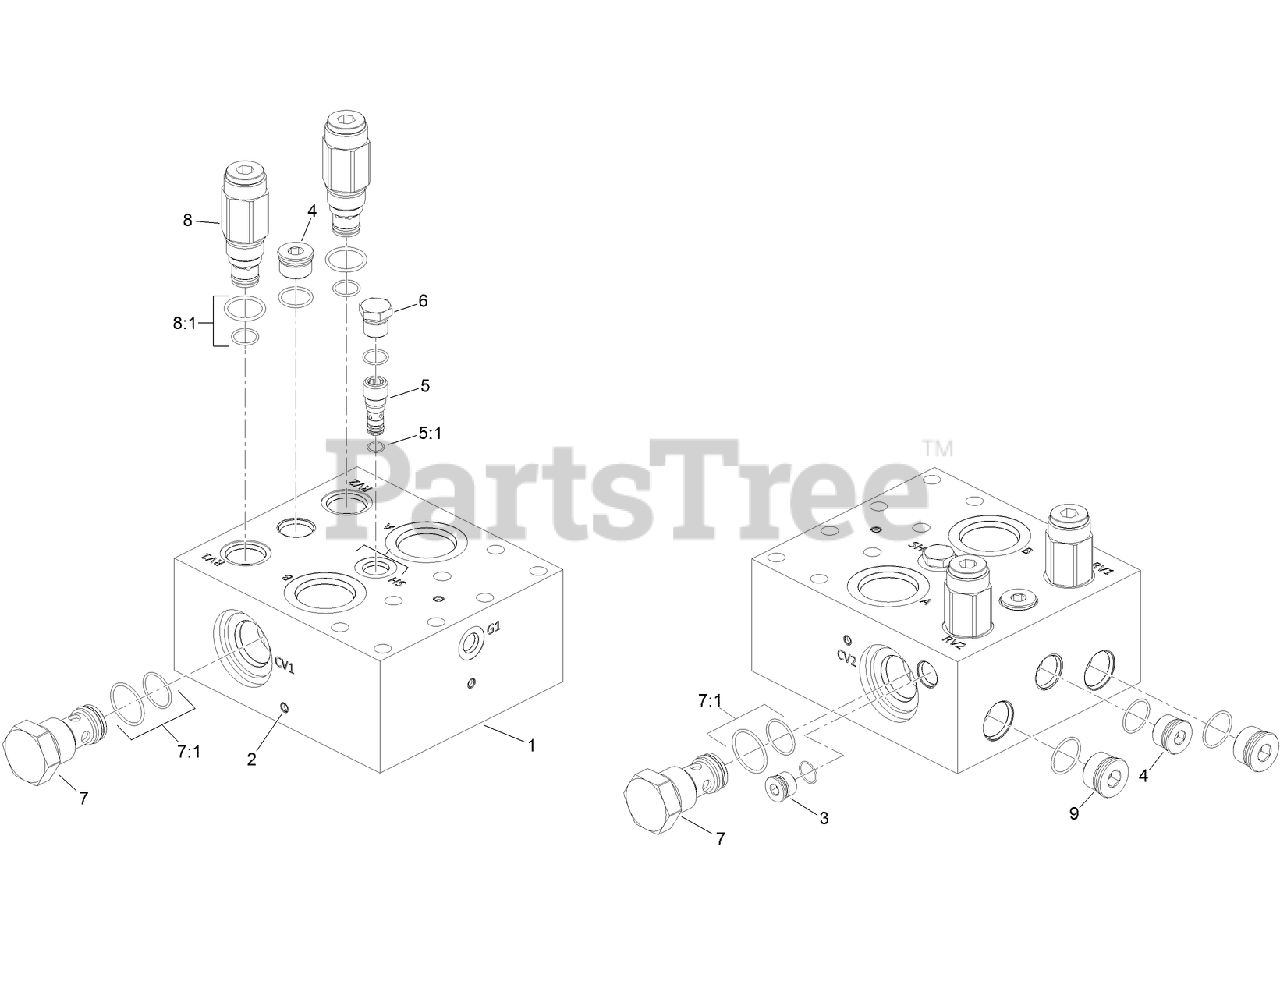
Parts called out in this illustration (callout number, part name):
1	BLOCK-MANIFOLD
2	Deck ASM
4	PLUG-HYD
5	VALVE-SHUTTLE
5:1	SEAL KIT
6	PLUG-LEAK, ZERO
7	VALVE-CHECK
7:1	SEAL KIT
8	VALVE-RELIEF, POPPET
8:1	SEAL KIT
9	PLUG-LEAK, ZERO
